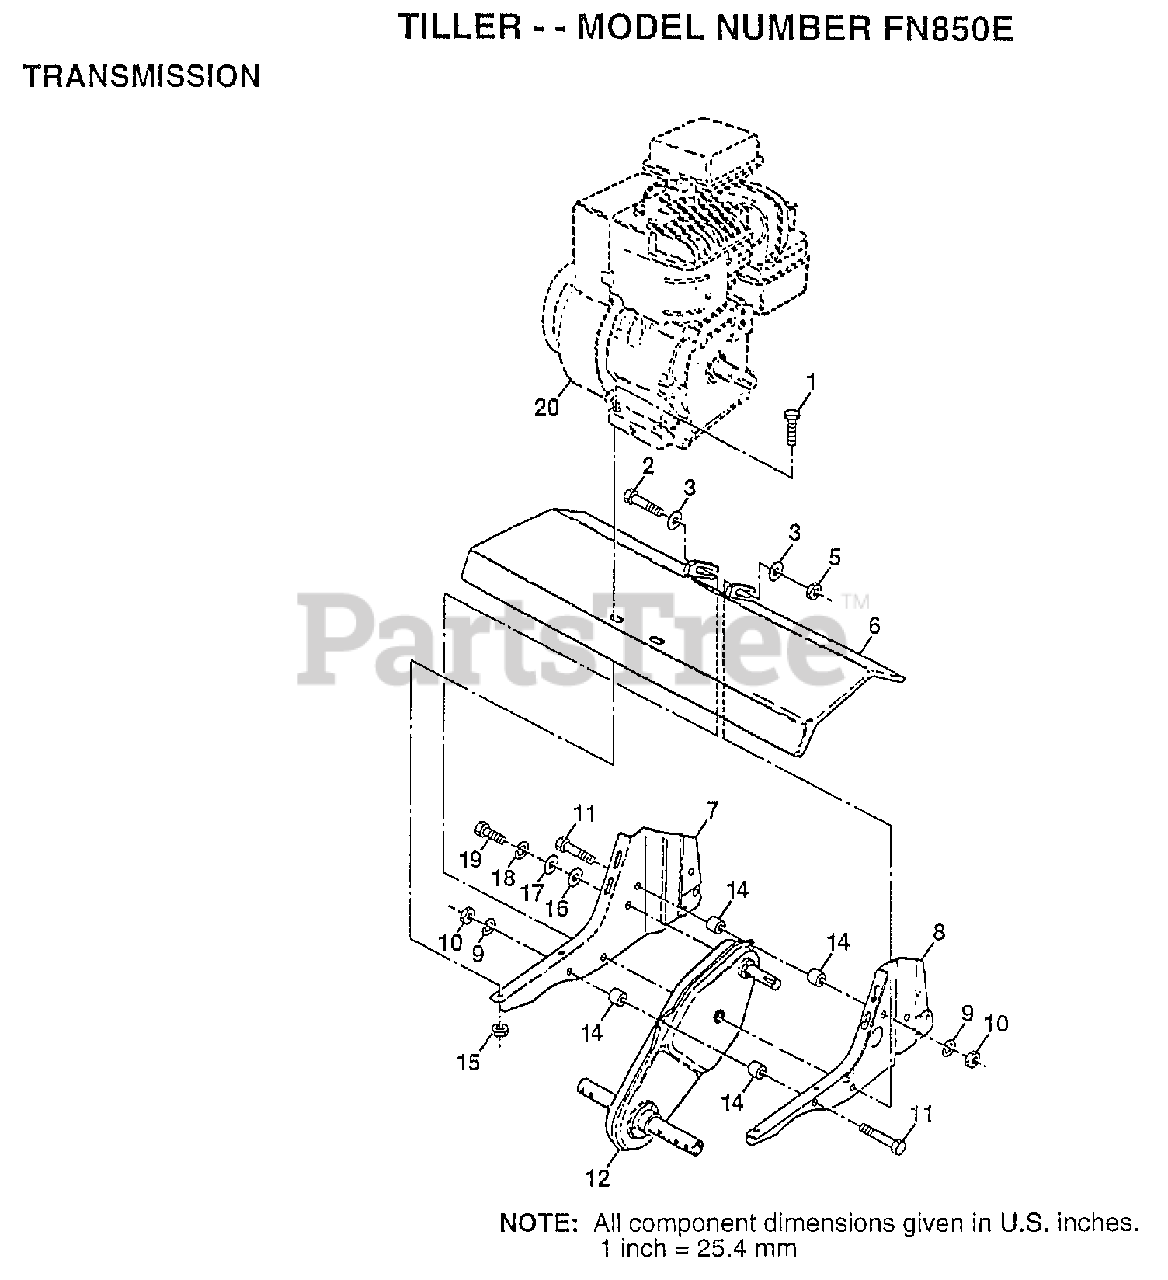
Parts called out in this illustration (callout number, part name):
1	BOLT.HEX.5/16-1.5
2	BOLT HEX 3/8-16
3	WASHER
5	NUT
6	"SHIELD, TINE"
8	BRACKET.ENG.LH.
9	LOCKWASHER
10	NUT.HEX.5/16-18
14	SPLIT SPACER RT
16	WASHER
17	WASHER
18	LOCKWASHER
19	BOLT
